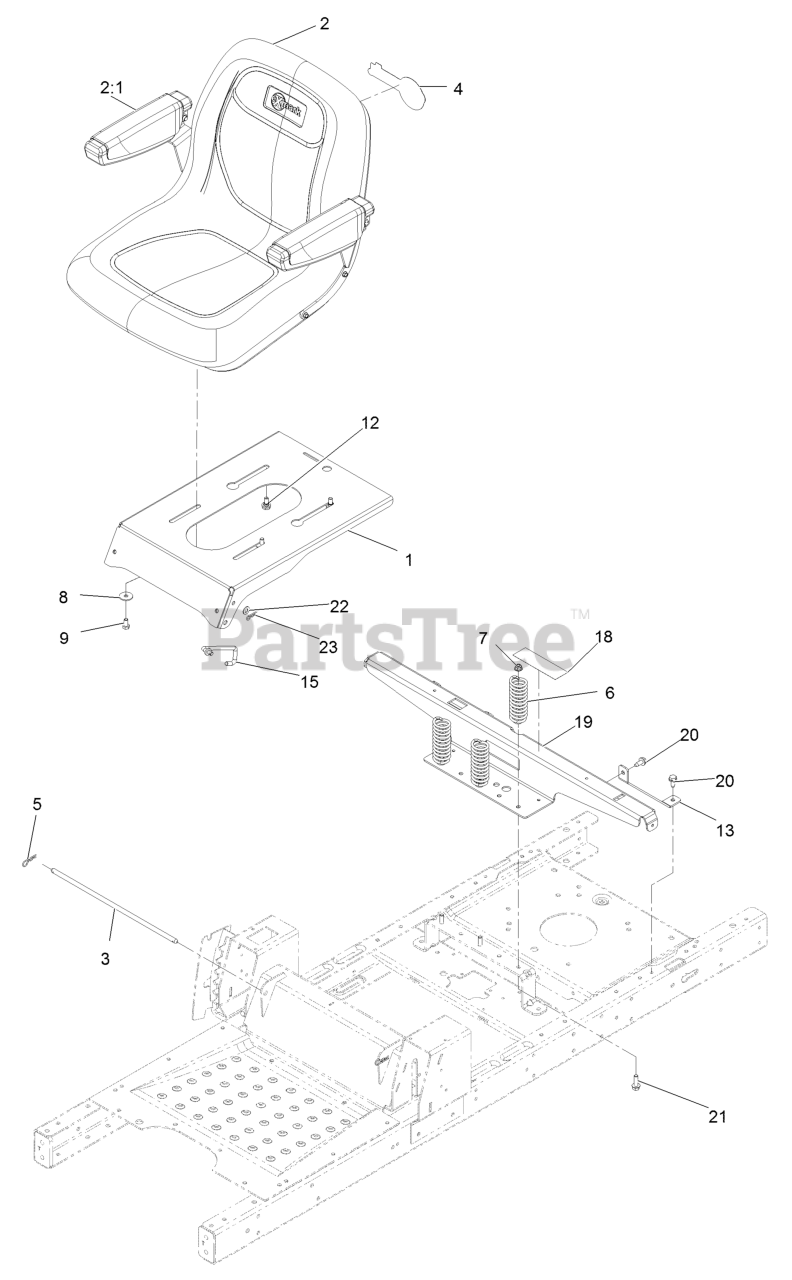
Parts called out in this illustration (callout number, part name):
2	SEAT-18 IN W/ARM
2:1	ARMREST KIT (MILSCO)
3	ROD-PIVOT, NARROW
5	PIN-COTTER
6	SPRING-COMPRESSION
7	NUT-HF, NI
8	WASHER-PIVOT
9	SCREW-HH
12	BOLT-SHOULDER,HFH
13	SUPPORT-TANK, REAR
15	STOP-SEAT
18	DECAL-SERVICE, CE
19	SUPPORT-POD
20	Screw-HWH 5/16-18 X 3/4 Tf
21	SCREW-HHF
22	WASHER-PLAIN
